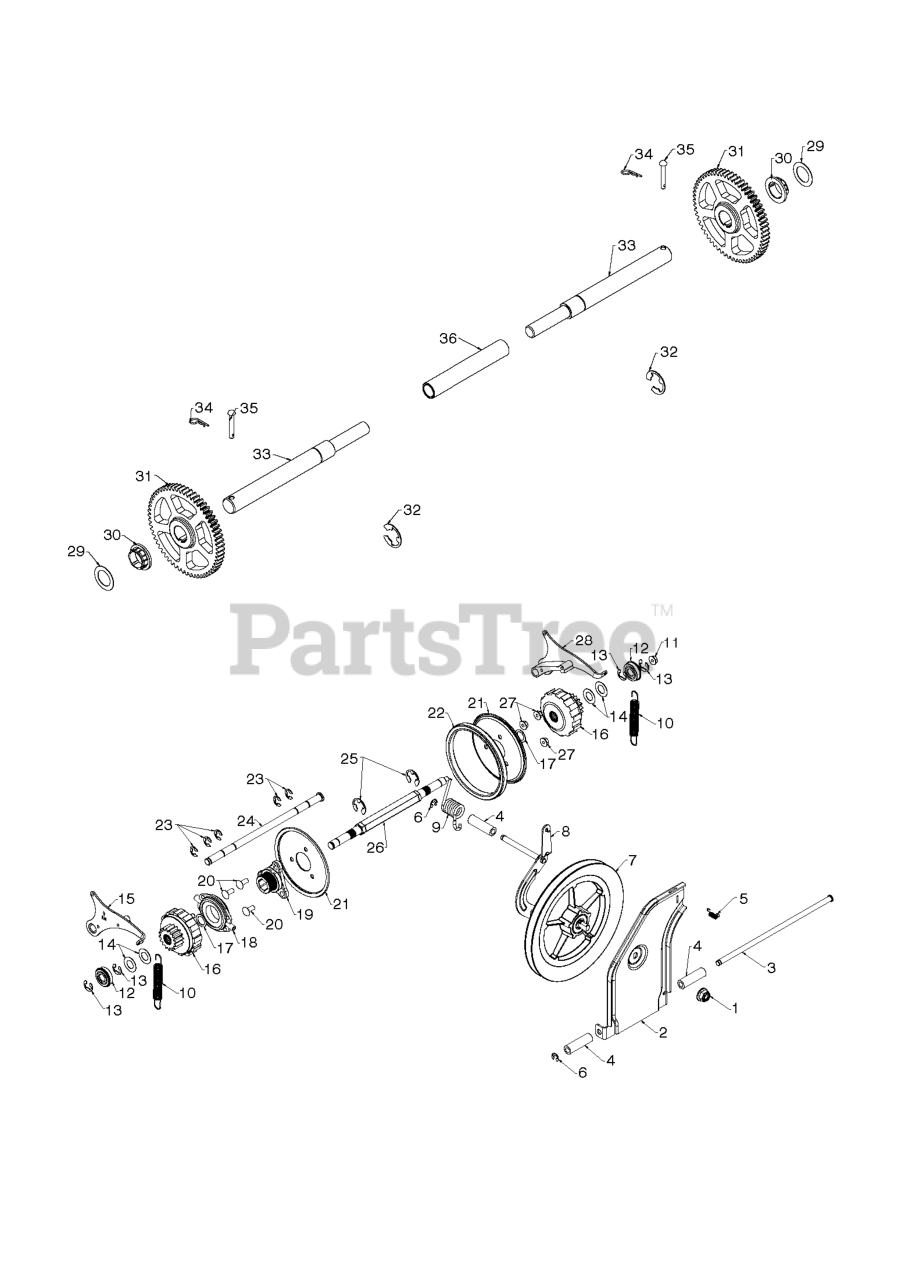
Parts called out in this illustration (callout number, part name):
1	NUT 1/2-13 HEX FLANGE NYLOK CL
2	PLATE.SWING.FRICTION PULLEY.47
2	PLATE SWING FRICTION PULL_MS
2	Plates
3	ROD.TIP.PLATE
3	ROD ROD,PIVOT, SWING PLATE ROD
4	SPACER YOKE, TORSION SPRING
5	SPRING LATCH
6	RETAINER RING E-RING CLEAR ZI
7	PULLEY ASSY TEXTURED TEXTURED
7	PULLEY.FRICTION.DISC.COMBO
8	BRACKET.YOKE.ASSEMBLY.479
8	BRACKET YOKE WELDMENT_MS 479
9	SPRING TORSION DRIVE
10	SPRING EXTENSION PS
11	NUT.HEX.FLANGE.LOCK.5/16-18
12	BEARING 9/16 ID. SNR
13	RING.RETAINING.1622-2RSNR.CLER
14	WASHER FLAT.637IDX1.00ODX21GA
15	PAWL.ASM.RH.SNOW
16	GEAR.ASM.PLANETARY
17	WASHER FLAT.59IDX1.065ODX25GA
18	BEARING HOUSING ASSY TRUNNION
19	HUB.RUBBER.WHEEL
20	BOLT.CARR.SQNK.5/16-18UNC.X3/4
21	PLATE.RUBBER.WHEEL.BLACK
22	RING RUBBER
22	Friction Drive
23	CLIP E-RING_.500 SHAFT
24	ROD ROD, PAWL ROD
26	SHAFT SHAFT, PWR STR SHAFT
27	NUT.HEX.FLANGE.LOCK.5/16-18
27	NUT.LOCK.5/16-18
28	PAWL.ASM.LH.SNOW
29	WASHER 1.00
30	BUSHING.HEX.1.SHAFT
30	BUSHING,HEX BUSHING (1
31	GEAR.59T
31	GEAR 59T DRIVEN PWR STR
32	E RING HYT
33	AXLE AXLE, SPLIT SHAFT
34	RETAINER M
35	RIVET
36	SLEEVE SLEEVE, AXLE SLEEVE
